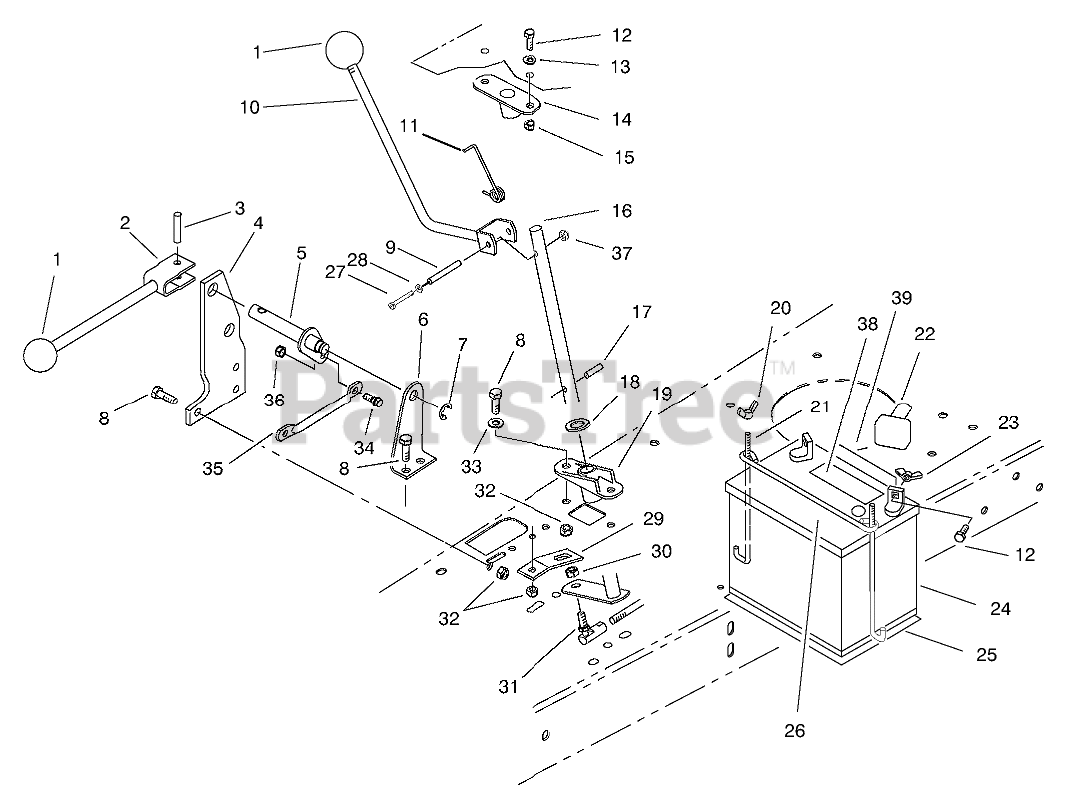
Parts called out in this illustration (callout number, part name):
2	ENGAGE LEVER WA
3	PIN-ROLL
4	PLTE - PIVOT OUTER
5	PIVOT SHAFT WA
6	BRKT - INNER PIVOT
7	RING-RETAINING, EXTERNAL
8	SCREW-HH
9	PIN-ROLL
10	SHIFT LEVER WA (BLACK)
11	SPRING-TORSION
12	SCREW-HH
13	WASHER-FLAT
14	SUPPORT-SHIFT SHAFT
15	NUT-LOCK, NI
16	SHAFT-SHIFT
17	PIN-SPRING
18	WASHER-THRUST
19	SUPPORT-LOWER SHIFTER
20	NUT-WING
21	POST-BATTERY
22	Boot
23	NUT-WING
24	Battery-12 Volt (Incl. Ref. #38 & 39)
25	PAD-SKID, ANTI
26	ROD-BATTERY HOLD DWN
27	SCREW-SPH
28	WASHER-FLAT
29	RETAINER-TRACTION SPRING
30	NUT-LOCK
31	JOINT-BALL
32	NUT-LOCK, NI
33	WASHER-PLAIN
34	SCREW-SHOULDER
35	LINK-BELLCRANK
36	NUT-HEX
37	NUT-HEX
38	Decal-Battery
39	Decal-Battery
